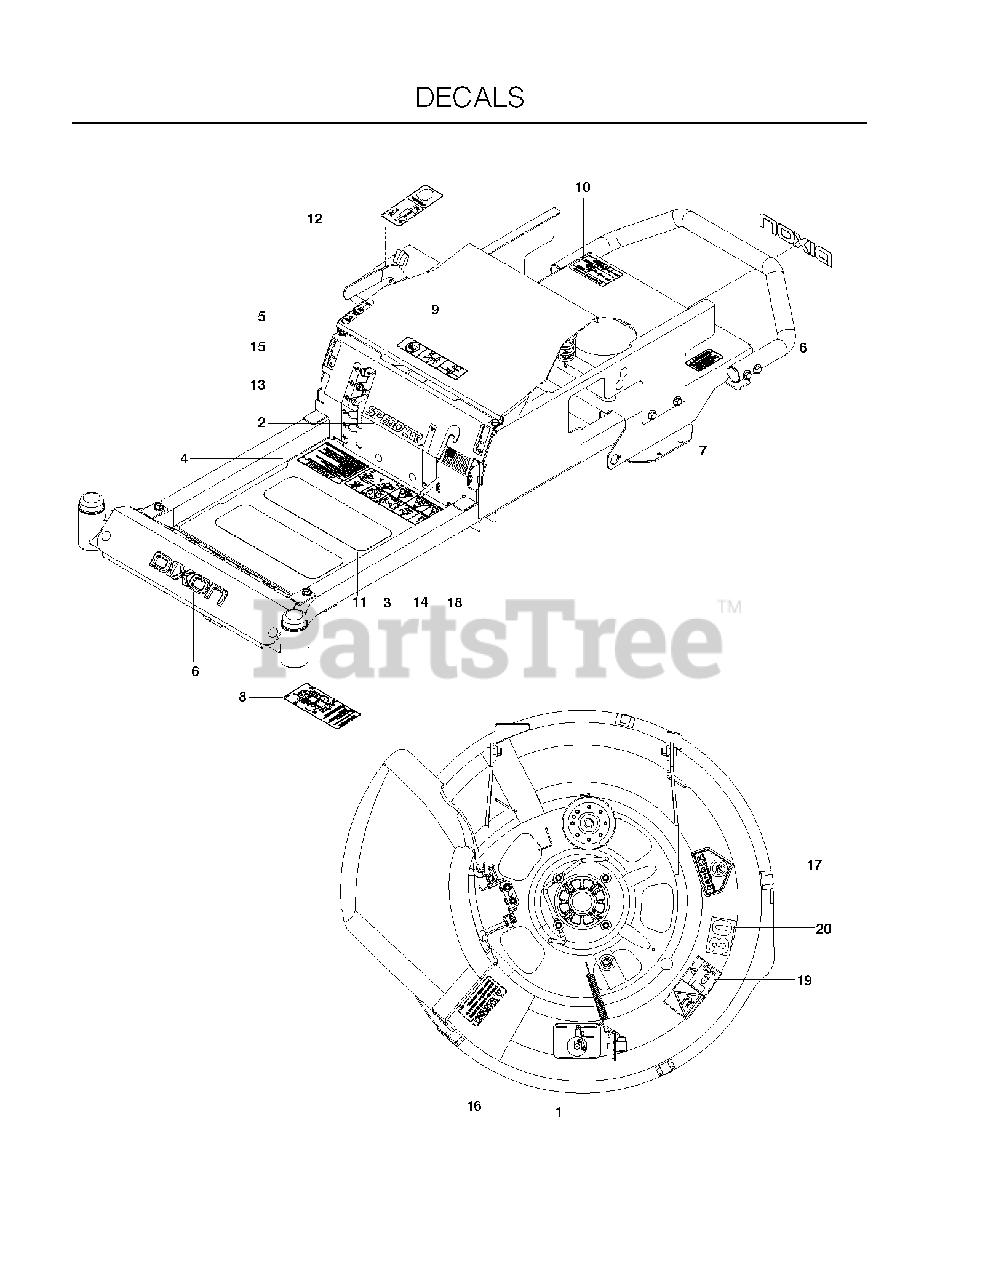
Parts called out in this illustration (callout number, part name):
1	DECAL, BELT ROUTING
2	DECAL, SPEEDZTR 6.5"
3	DECAL, SAFETY WARNING
4	DECAL, WARNING
5	DECAL, PARK BRAKE
6	DECAL, DIXON LOGO, DOMED
7	DECAL, PROP. 65
8	DECAL, SERVICE
9	DECAL, BATTERY
10	DECAL, DO NOT MOUNT
11	ANTI-SKID PAD
12	DECAL, CONTROL PANEL
13	DECAL, DECK HEIGHT
14	DECAL, BLADE ENGAGEMENT
15	DECAL, MOTION CONTROL
16	DECAL, CAUTION
17	DECAL, CPSC
18	DECAL, FLAG
19	DECAL, EURO SEVERING
20	DECAL, 30"
